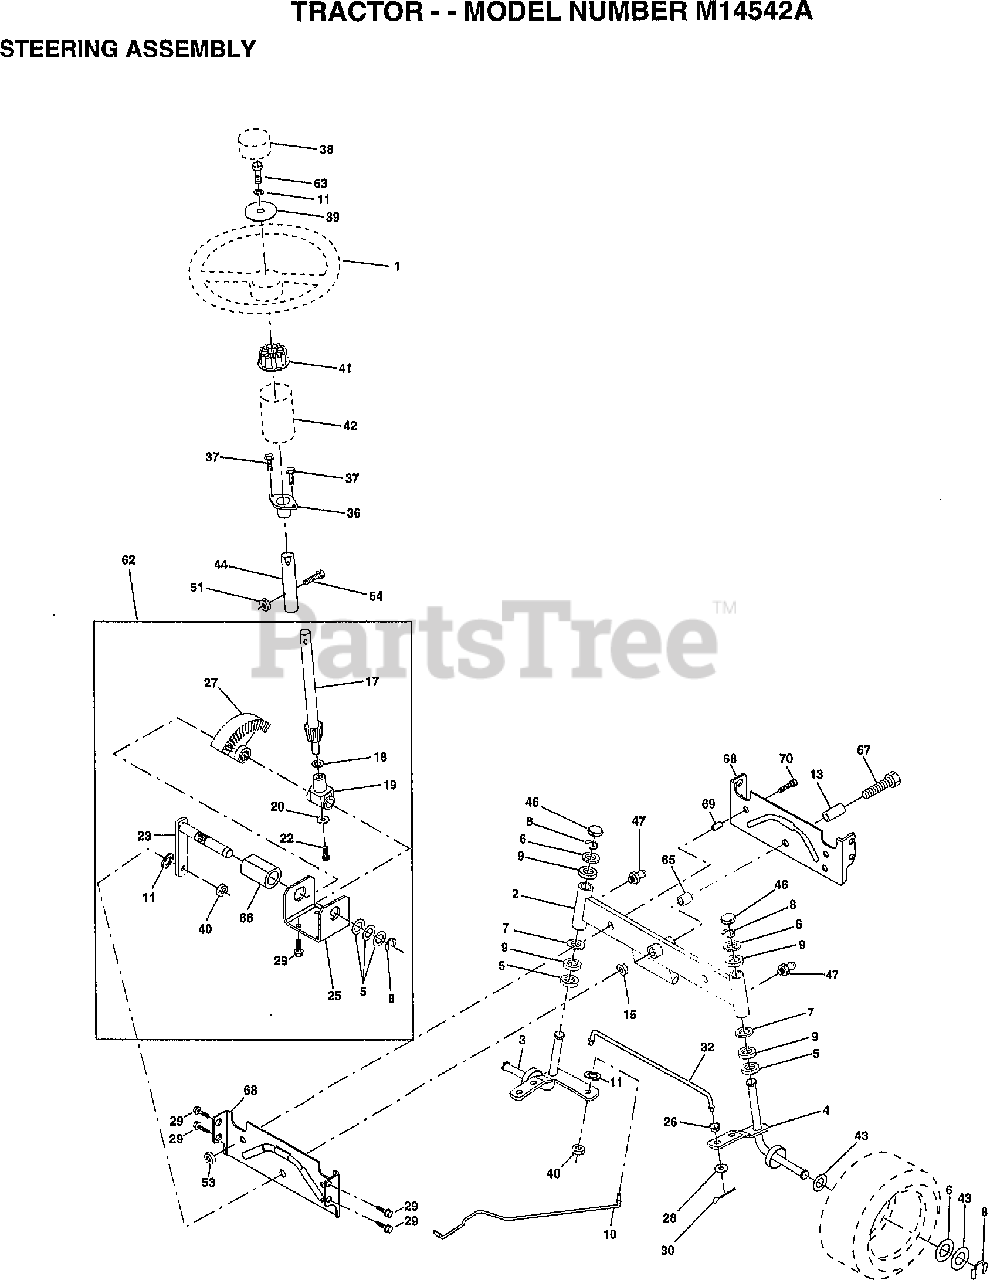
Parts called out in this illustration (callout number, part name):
1	WHEEL STR AYP BLK
2	AXLE ASM
3	SPINDLE.ASM.LH
4	"SPINDLE ASM,RH"
5	WASHER .T
6	WASHER
7	WASHER
8	RING
9	COL. SRTG. BEAR.
10	DRAGLINK-STAMPED
11	LOCKWASHER
13	BEARING AXLE
15	"NUT-LOC,FLANGE LT"
17	SHAFT ASM STEERIN
18	THRUST WASHER
19	SUPPORT.SHAFT
22	SCREW HEX SOC1/4-
25	BRKT-STEERING
26	BUSHING.DRAGLINK
27	GEAR SECTOR
28	WASHER
29	SCREW
30	COTTER PIN
32	TIE ROD
36	BUSHING.STEERING
37	"SCREW-TT,10-32 FL"
38	CAP STEER AYP
39	WASHER T
40	GRIPCO NUT
41	ADAPTER LT
42	BOOT.STEER.PL
43	WASHER
44	EXT SHAFT STEERIN
46	CAP
47	ZERK M
51	NUT
54	BOLT
62	KIT STEERING ASM
63	BOLT
65	SPACER AXLE
66	"BEARING-ARM,PITMA"
67	BOLT
68	BRACE AXLE
69	"SPACER BRCAE,AXLE"
70	BOLT.HEX.3/8-16X2
